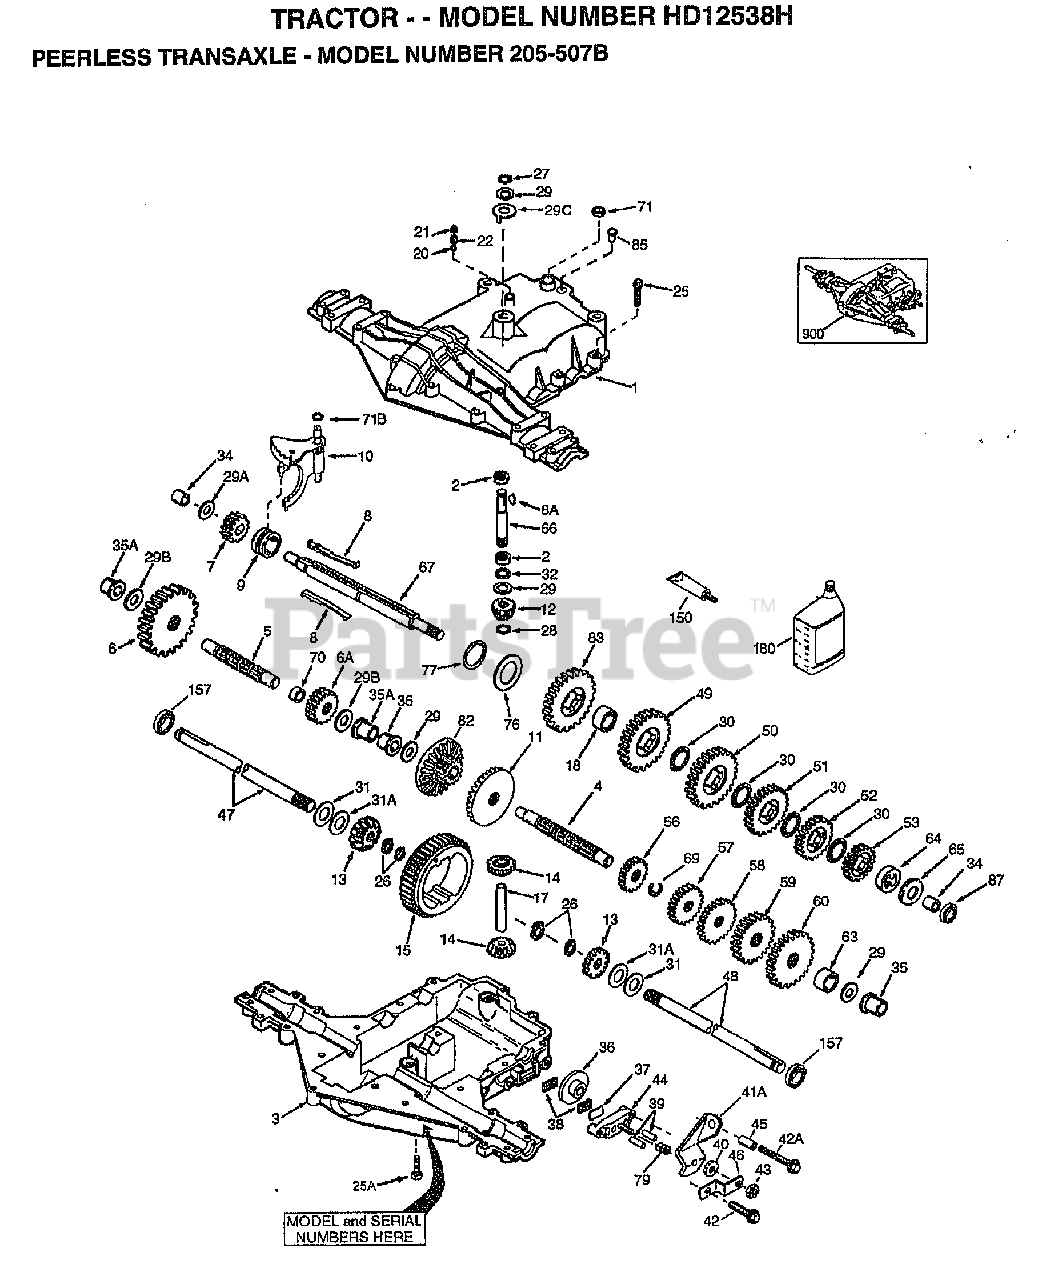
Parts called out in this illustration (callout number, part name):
1	TRANSAXLE COVER
2	NEEDLE BEARING 5/8" ID
3	TRANSAXLE CASE
4	COUNTERSHAFT
5	OUTPUT SHAFT
6	SPUR GEAR (38 TEETH)
6A	SPUR GEAR (15 TEETH)
7	SPUR GEAR (11 TEETH)
8A	KEY, WOODRUFF
9	COLLAR, SHIFTER
10	SHIFT ROD & FORK
11	BEVEL GEAR (30 TEETH)
12	INPUT BEVEL PINION (13TEETH)
13	BEVEL GEAR (13 TEETH)
14	BEVEL PINION (13 TEETH)
15	RING GEAR (43 TEETH)
18	SPACER, NEUTRAL
20	BALL STEEL, 5/16" DIA.
21	SCREW, 3/8-16 X 3/8"
25A	SCREW 1/4-20 X 1-3/8"
26	RING RETAINER
27	RING, RETAINER
28	RETAINING RING
29	WASHER THRUST
29B	WASHER THRUST
29C	P/N CONFLICT - CHECK WITH SUPPLIER
30	WASHER THRUST
31A	FLAT WASHER
32	OIL SEAL 5/8"
34	BUSHING 9/16"
35	FLANGED BUSHING 5/8" ID
35A	FLANGED BUSHING 3/4"
37	PLATE BRAKE PAD
41A	BRAKE LEVER
42A	SCREW, 1/4-20 X 2-1/4
43	LOCKNUT 5/16-24
44	HOLDER BRAKE PAD
46	BRKT BRAKE LEVER
49	SPUR GEAR (29 TEETH)
50	SPUR GEAR (23 TEETH)
51	SPUR GEAR (19 TEETH)
52	SPUR GEAR (16 TEETH)
53	SPUR GEAR (15 TEETH)
56	SPUR GEAR (11 TEETH)
57	SPUR GEAR (17 TEETH)
58	SPUR GEAR (21 TEETH)
59	SPUR GEAR (24 TEETH)
60	SPUR GEAR (25 TEETH)
66	INPUT SHAFT
67	SHIFTER & BRAKE SHAFT
69	RETAINING RING
70	SPACER .890
71	SEAL SQUARE CUT
76	WASHER, THRUST
77	INVERTED RETAINING RING
82	BEVEL & SPUR GEAR (30 & 13 TEETH)
83	SPUR GEAR (27 TEETH)
85	OIL FILL PLUG
87	OIL SEAL 9/16"
150	LIQUID GASKET RTV SILICONE
157	OIL SEAL 3/4"
180	GEAR OIL 80W90
